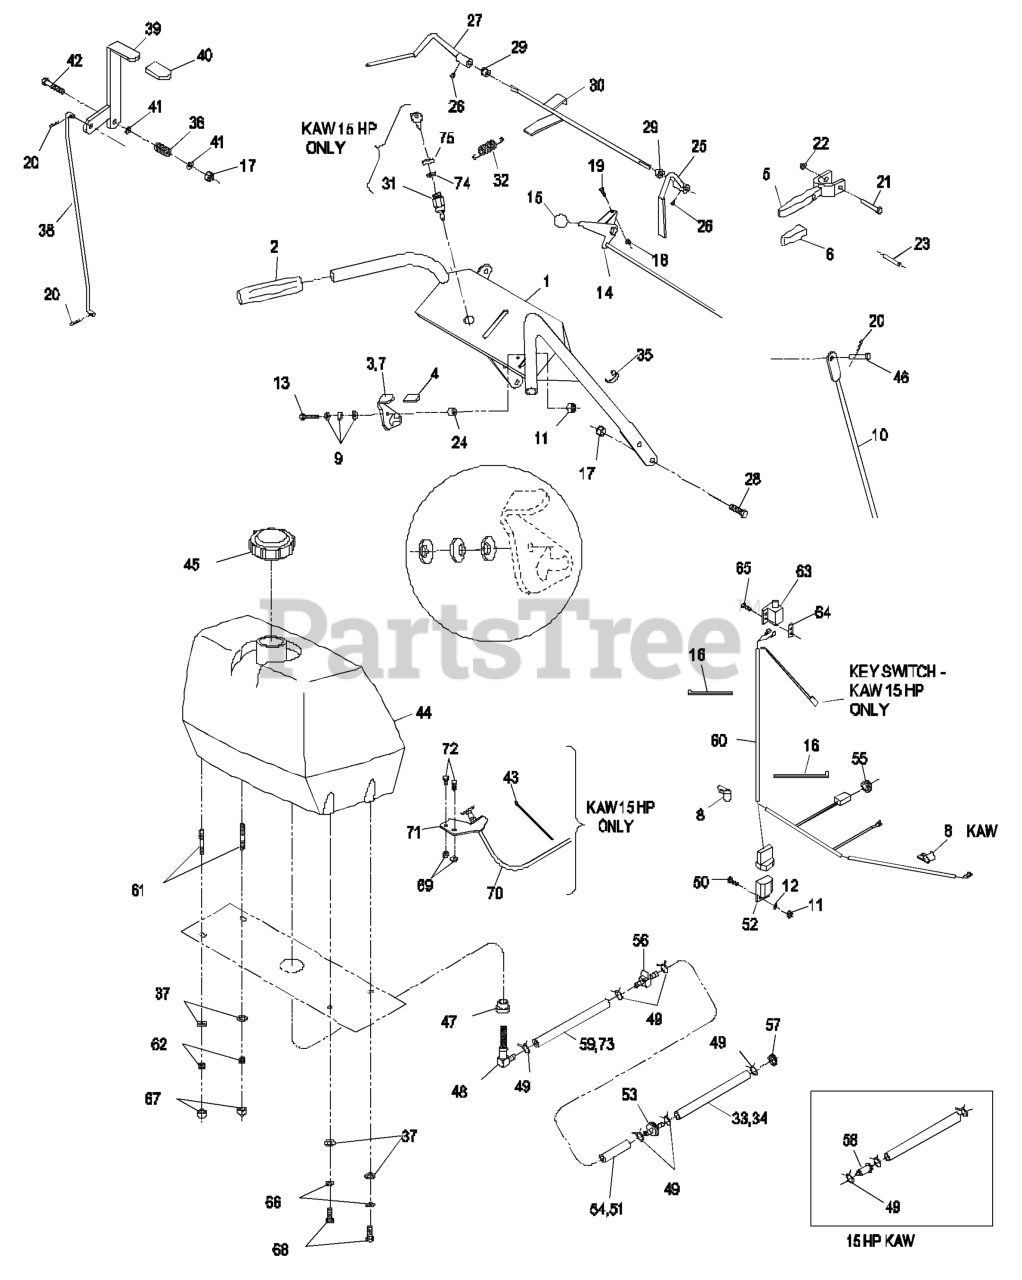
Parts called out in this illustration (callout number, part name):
1	KIT,HANDLE/DECALS METRO
4	GRIP-LATCH
5	DRIVE LEVER ASM
6	GRIP-LEVER, DRIVE
8	CLIP-LOOM
9	WASHER-SPRING
10	LINKAGE-WHEEL, DRIVE
11	NUT-LOCK, NI
12	WASHER-FLAT
13	SCREW-HH
14	CABLE-CONTROL, THROTTLE
15	KNOB-BALL
16	TIE-CABLE
17	NUT-LOCK, NI
18	NUT-LOCK, NI
19	BOLT-CARR
20	PIN-COTTER
21	PIN-LEVER, DRIVE
22	NUT-PUSH
23	PIN-ROLL
25	LEVER-RH
26	SCREW-SET
27	LEVER-LH
28	SCREW-HH
29	BUSHING-NYLON
30	WLD,ROD OPC
31	SWITCH & KEY (INCLUDES NU
32	SPRING-EXTENSION
33	HOSE-FUEL
34	HOSE-LINE, FUEL
35	CLIP-CABLE
36	SPRING-COMPRESSION
37	WASHER-PLAIN
38	LINKAGE-BLADE, UPPER
40	GRIP-LEVER
41	WASHER-FLAT
42	SCREW-HH
43	TIE-PLASTIC
45	CAP-FUEL
46	PIN-CLEVIS
48	ELBOW-TANK, FUEL
50	SCREW-HH
51	HOSE-FUEL
52	MODULE-INTERLOCK
54	HOSE-LINE, FUEL
55	GROMMET
56	VALVE-FUEL
57	CLAMP-HOSE
58	Kawasaki P/N 41019-1055 W/6" Fuel Line
59	HOSE-FUEL
60	HARNESS-WIRING
62	SPRING-TANK, FUEL
63	SWITCH-OPEN, NORMALLY
64	PLATE-TAPPED
65	SCREW-PPH
66	WASHER-LOCK
67	NUT-LOCK, NI
68	SCREW-HH
70	CABLE-CHOKE
71	BRACKET-CABLE, CHOKE
72	SCREW-HH
73	HOSE-FUEL
74	NUT-SWITCH, IGNITION
75	Seal, Ignition Switch (15 Hp Kaw)
